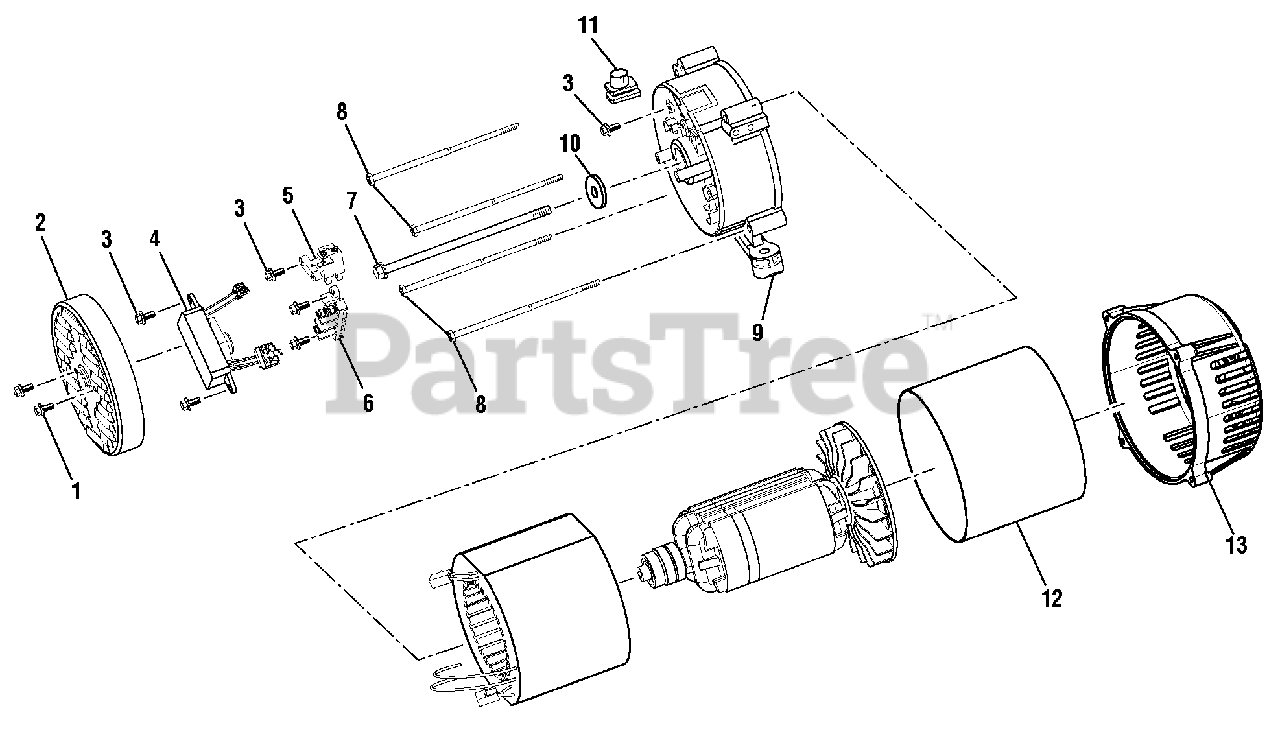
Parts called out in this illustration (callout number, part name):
1	Bolt (M5 x 10 mm, Hex Hd.)
2	Brush Cover
3	Bolt (M5 x 16 mm, Hex Hd.)
4	Automatic Voltage Regulator
5	Brush Assembly
6	Terminal Block
7	Bolt (5/16-24 x 182 mm, Hex Hd.)
8	Bolt (M6 x 180 mm, Hex Hd.)
9	Bearing Housing
10	Washer (ID8.4 x OD25.1 x 3t)
11	Rubber Boot
12	Generator Head Cover
13	Adaptor Housing
